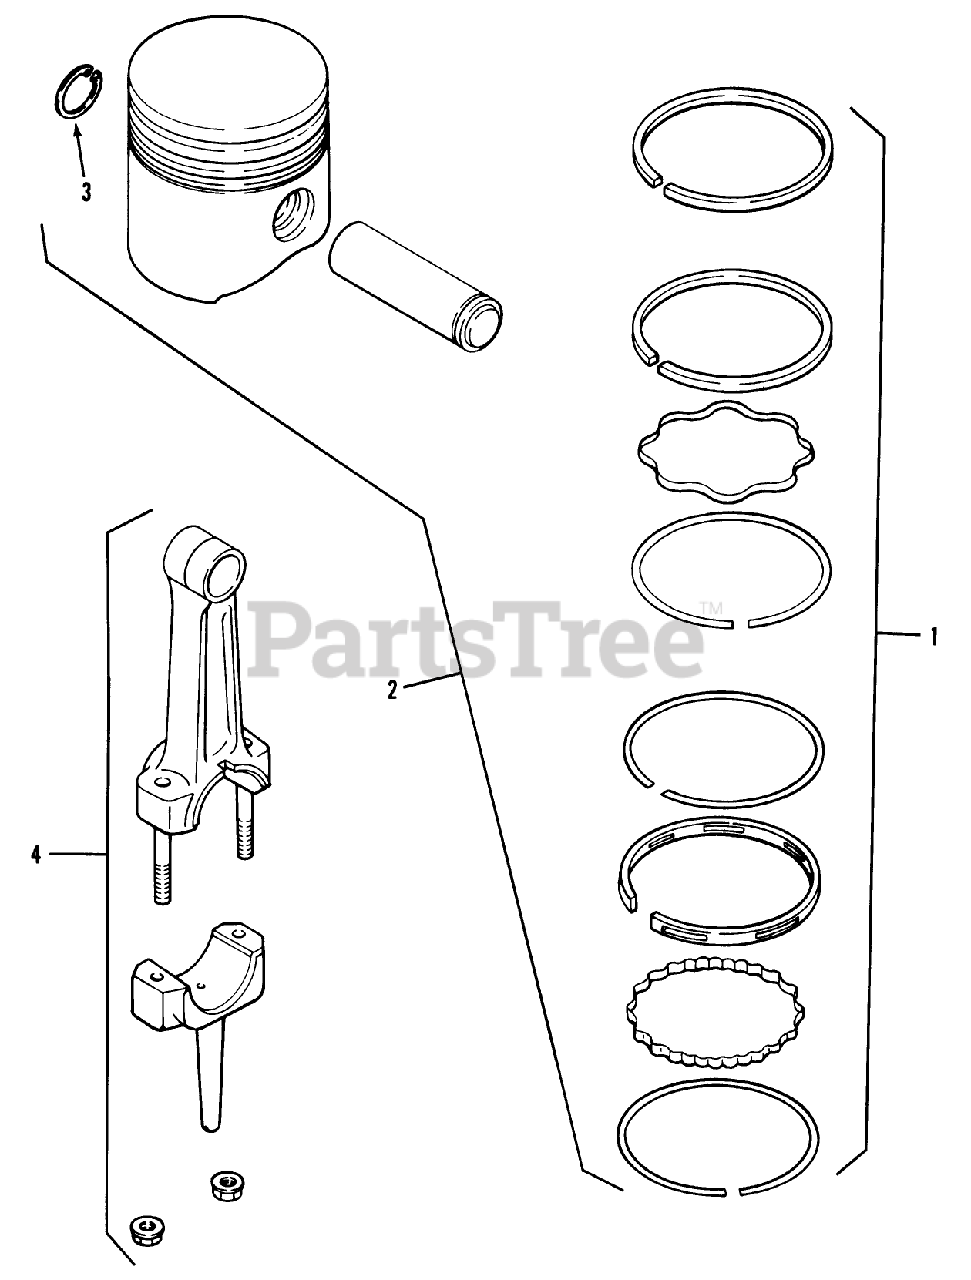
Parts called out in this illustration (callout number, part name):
1	KOHLER 235287
2	KOHLER 47-874.01
3	KOHLER 47-018-01
4	KOHLER 47-067-13
